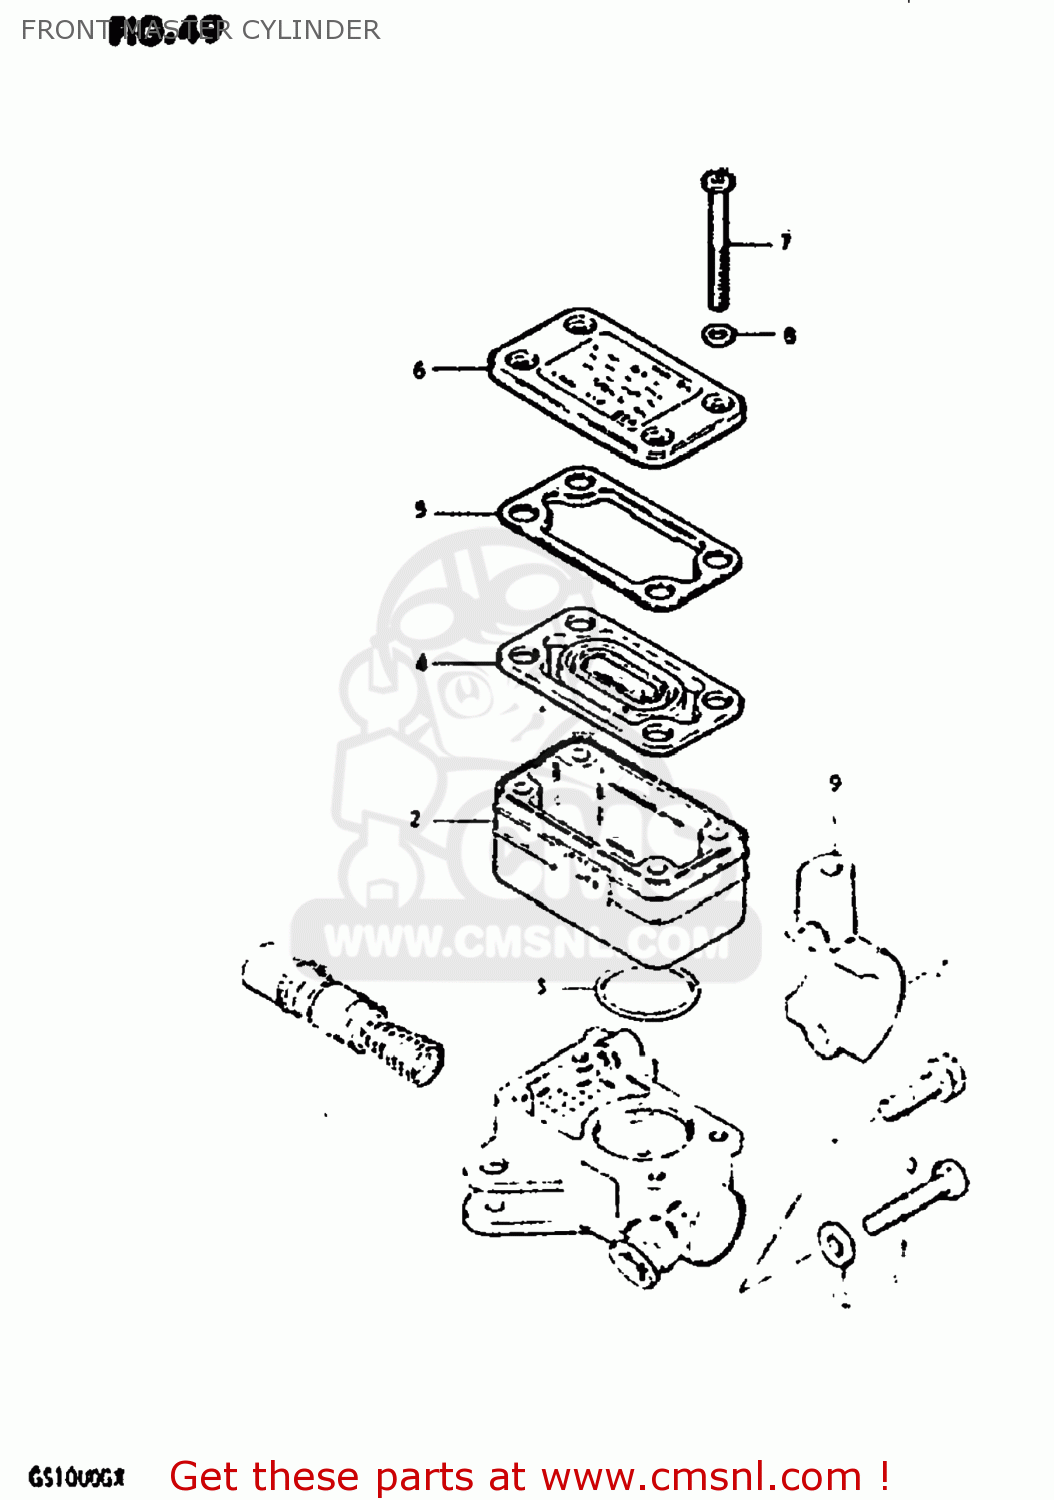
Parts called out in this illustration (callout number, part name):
1	PISTON & CUP SET
2	RESERVOIR
3	O RING
4	DIAPHRAGM
5	PLATE,DIAPHRAGM
6	CAP
7	SCREW
8	WASHER
9	HOLDER
10	BOLT,MASTER CYLINDER H
11	BOLT
12	WASHER
